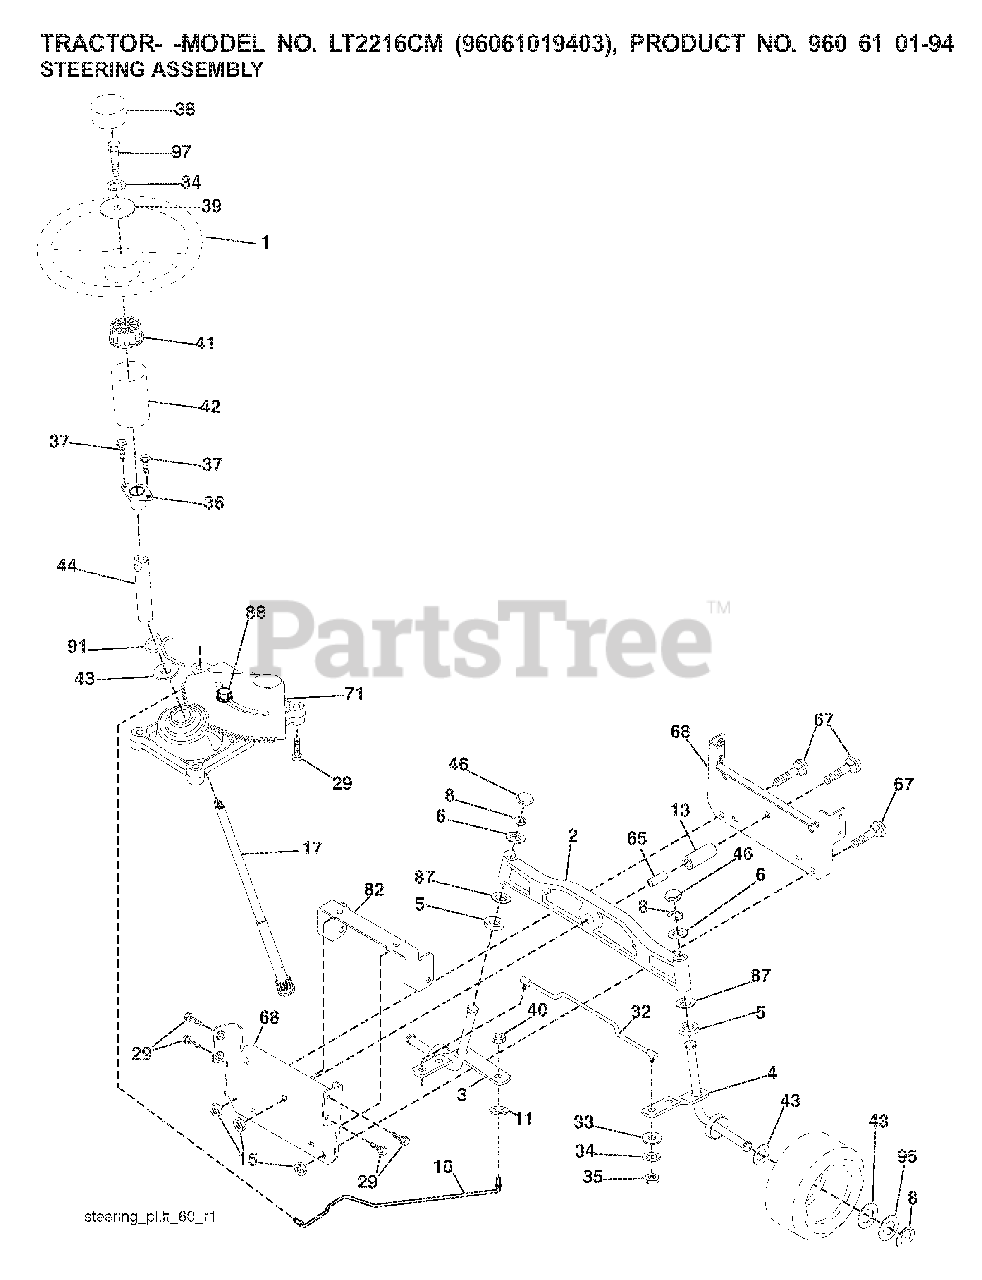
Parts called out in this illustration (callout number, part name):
1	WHEEL.STEERING.PREM.2.BLK
2	AXLE ASSY FRONT
3	SPINDLE.ASM.LH.15"TIRES
4	SPINDLE.ASM.RH.15"TIRES
8	RING CLIP
10	DRAGLINK.15".TIRES.2001
11	WASHER, LOCK 3/8
13	TUBE, PIVOT AXLE
15	NUT
17	SHAFT STEERING SPLINE
29	SCREW, 3/8-16X3/4
32	ROD.ASM.TIE.BALL.JOINT.NOVAN
33	WASHER M
34	LOCKWASHER
35	NUT, CROWNLOCK
36	BUSHING, STEERING
38	INSERT.CAP.STRG.WH.BLACK
39	WASHER.11/32
40	NUT CROWNLOCK 3/8-24
41	ADAPTER, WHEEL STNG..
42	BOOT.STEERING.SHAFT.BLACK
44	SHAFT.EXTEN.STRG.SPLINE
46	CAP.SPINDLE
65	SPACER BRACE AXLE
67	BOLT CARRIAGE
68	BRACE.AXLE.15"TIRES
71	STEERING ASM
82	BRACKET.SUSP.CHASSIS.FRONT.15
87	WASHER, FLAT .781 X 1 1/2"
88	BOLT, SHOULDER 7/16-20
91	CLIP.STEERING
95	WASHER.HARDENED
118	BUSHING, AXLE CAST
